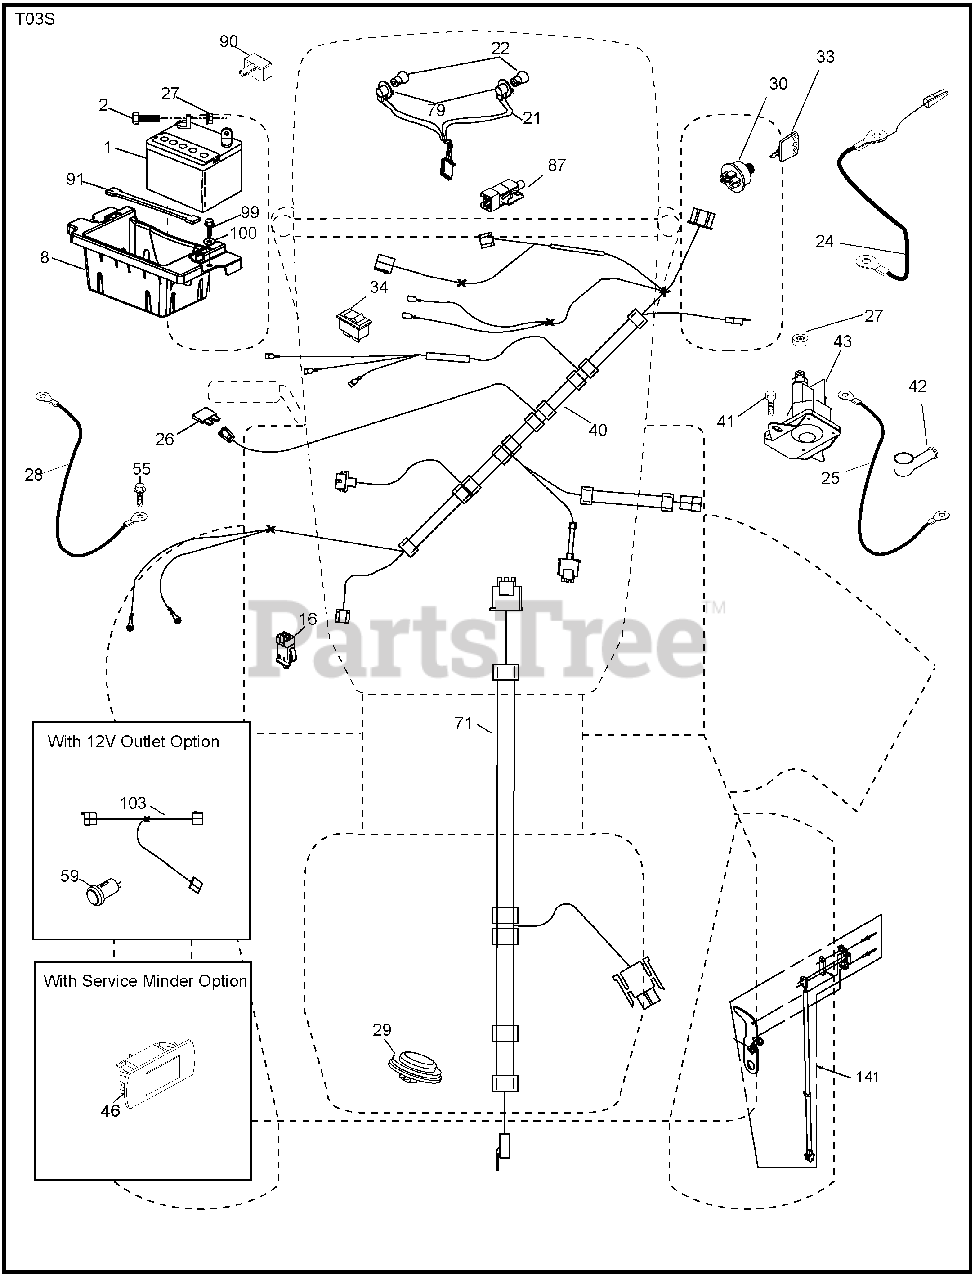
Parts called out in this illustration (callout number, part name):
1	Battery
2	Bolt Hex Head 1/4-20 x 3/4
8	Box Battery
16	Switch Interlock Push-In
21	Harness Socket Light w/4152J
22	Bulb Light
24	Cable Battery
25	Cable Starter
26	Fuse
27	Nut Keps Hex 1/4-20 unc
28	Cable, Ground
29	Switch, Seat
30	Switch, Ignition
33	Key/Chain
34	Switch Light/Reset
40	Harness Ignition Dash
41	Screw Thd Cut 1/4-20 x 1/2
42	Cover, Terminal
43	Solenoid
46	Gauge SRVCMNDR HRMTR
55	Screw Thdrol 5/16-18 x 3/4 TYTT
71	Harness Ignition
79	Socket Asm Bulb Twistlock
87	Switch Interlock Clutch Cable
90	Cover Terminal Battery
91	Strap Battery
99	Screw 1/4-20 x 3/4
100	Washer 9/32 x 7/8 x 16
102	Harness Pigtail
105	Switch Reverse
141	Kit ROS
